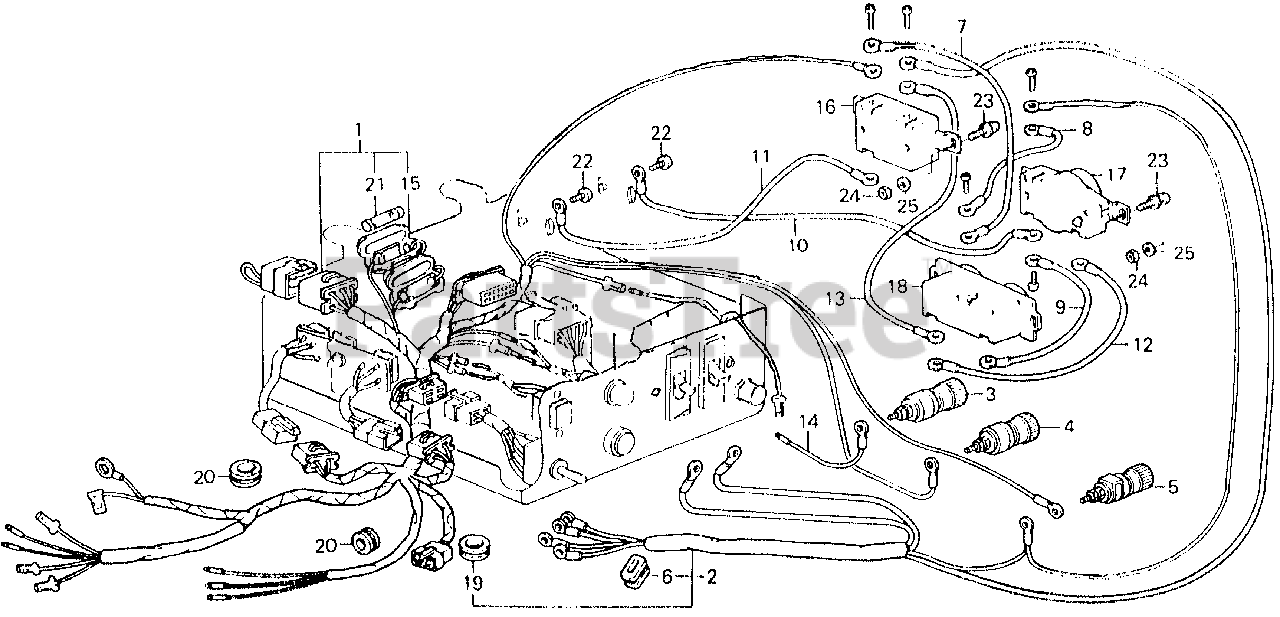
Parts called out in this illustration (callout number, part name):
1	WIRE HARNESS, BOX (NOT AVAILABLE)
2	WIRE, A.C. OUTLET
3	TERMINAL, D.C. OUT (+)
4	TERMINAL, D.C. OUT (-)
5	TERMINAL ASSY., GROUND (NOT AVAILABLE)
6	GROMMET, A.C. WIRE
7	WIRE, RECEPTACLE CONNECTING (200)
8	WIRE, RECEPTACLE CONNECTING (100)
9	WIRE, RECEPTACLE CONNECTING (100) (NOT AVAILABLE)
10	WIRE, RECEPTACLE CIRCUIT BREAKER CONNECTING (100)
11	WIRE, RECEPTACLE CIRCUIT BREAKER CONNECTING (200)
12	WIRE, RECEPTACLE CONNECTING (100) (GROUND) (NOT AVAILABLE)
13	WIRE, RECEPTACLE CONNECTING (200) (GROUND)
14	WIRE, D.C. OUT
15	CASE, FUSE CONNECTOR
16	RECEPTACLE (20A-250V)
17	RECEPTACLE (30A 250V)
18	RECEPTACLE (15A-125V)
19	GROMMET B, TUBE
20	GROMMET, WIRE HARNESS
21	FUSE (5A)
21	FUSE B (5A)
22	SCREW, PAN (5X8)
23	SCREW-WASHER (4X12)
24	NUT, HEX. (4MM)
25	WASHER, PLAIN (4MM)
